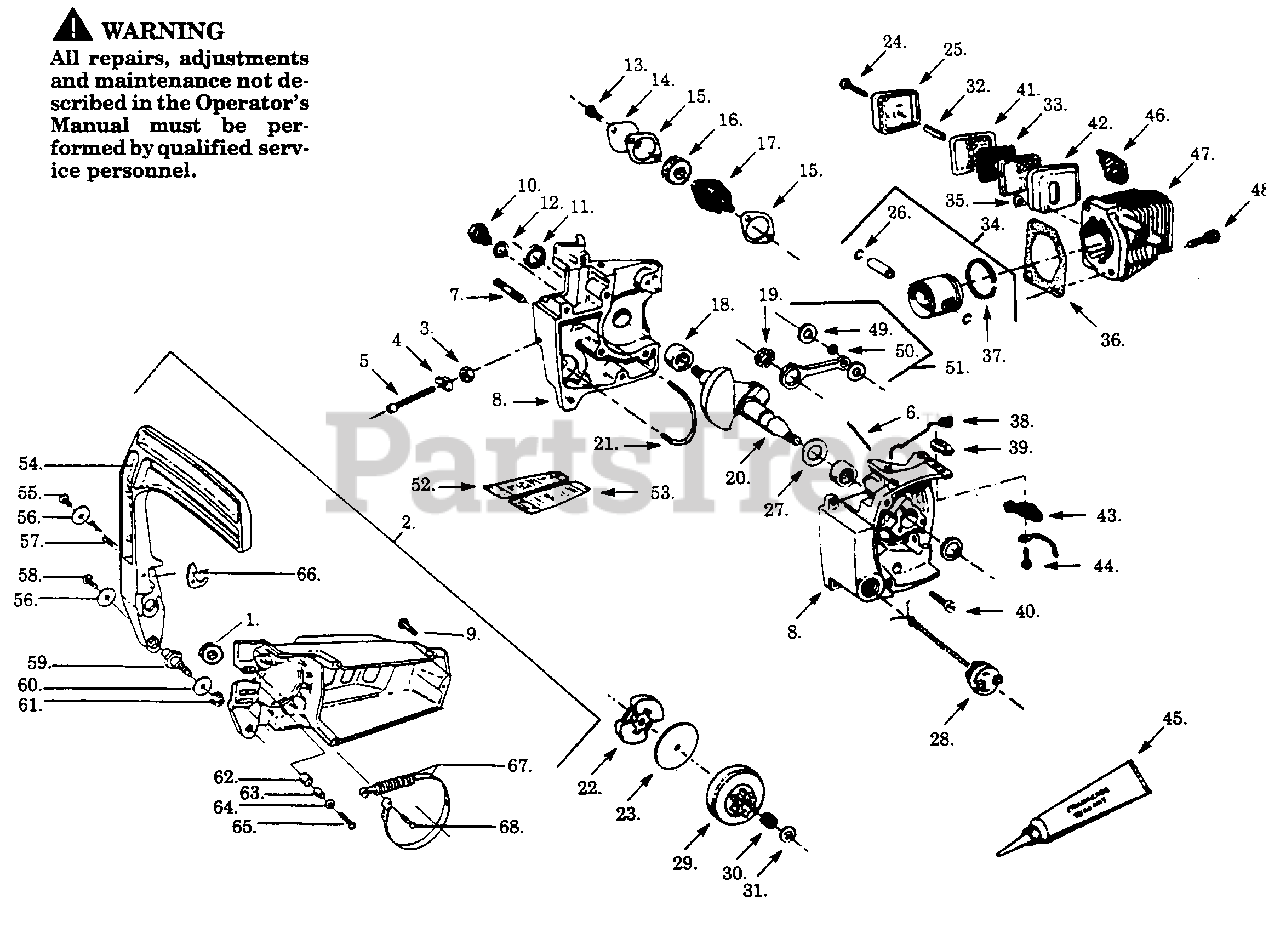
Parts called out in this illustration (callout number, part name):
1	Bar Mounting Nut
2	Chainbrake Ass'y.
3	Lock Nut
4	Bar Adjust Pin
5	Screw
6	Oil Tank Vent Pin
7	Bar Mounting Stud
8	Crankcase Ass'y. (Inc.3-7,10,11,18)
10	Check Valve Kit (Inc. 12)
11	Crankshaft Seal
12	Check Valve Gasket
14	Metering Body Cover
15	Metering Body Gasket
16	Oil Filter
17	Metering Body Ass'y.
18	Crankshaft Bearing
19	Roller Bearings (Inc. 12 bearings)
20	Crankshaft
21	Oil Discharge Line
22	Clutch Ass'y. Kit
23	Clutch Washer Kit
25	Muffler Cover
26	Piston Pin Retainer
27	Thrust Washer
28	Oil Cap Ass'y.
29	Clutch Drum
30	Clutch Bearing
31	Clutch Spacer
33	Spark Arrestor Screen
34	Piston Kit (Inc.26,37,&Pin)
36	Cylinder Gasket
37	Piston Ring
38	Switch Knob Ass'y.
39	Ramp Switch
41	Muffler Baffle
42	Muffler Body
43	Switch Clamp
45	Crankcase Sealant
46	Spark Plug CJ-8
47	Cylinder
50	Bearing Rod
51	Connecting Rod Ass'y. Kit
52	Instruction Decal Right Hand (Not a serviceable part)
53	Instruction Decal Left Hand (Not a serviceable part)
54	Actuating Lever
56	Handguard Washer
57	Handguard Pin
59	Handguard Pivot
61	Bar Mounting Nut
62	Roller Latch Sleeve
63	Latch Roller
64	Roller Latch Washer
65	Latch Pin
67	Brake Band Ass'y.
68	Band Anchor Pin
